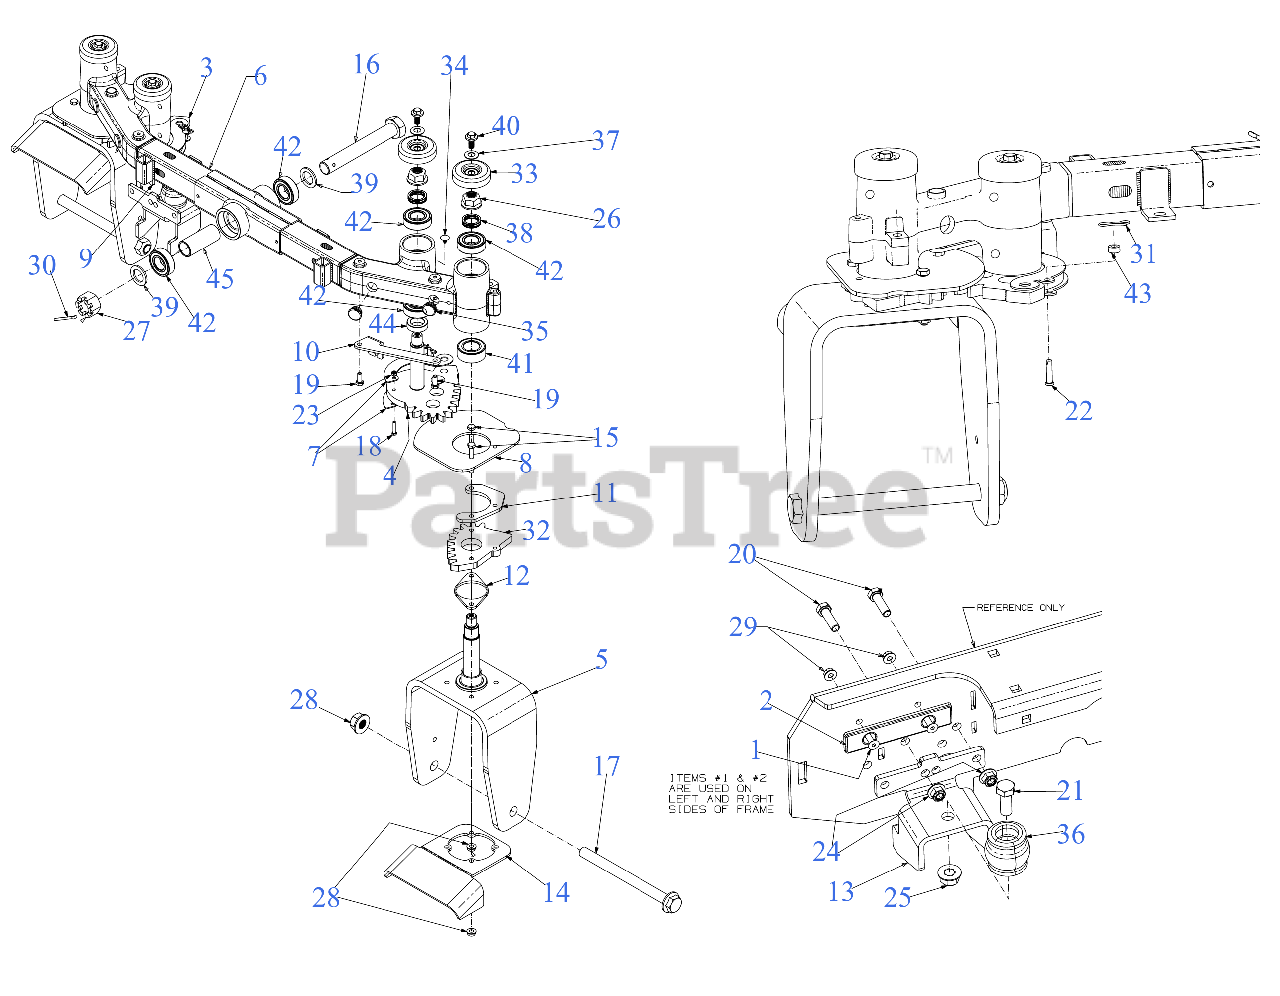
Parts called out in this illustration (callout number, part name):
1	SCREW-FLAT HEAD CA
2	PLATE-LIFT WEAR
3	LEFT HAND STEERING GEAR ASSEMBLY
4	RIGHT HAND STEERING GEAR ASSEMBLY
5	YOKE ASSEMBLY
6	AXLE ASSEMBLY
12	LOWER GEAR SPACER PLATE
13	BUMPER MOUNTING BRACKET
15	HEX SCREW 5/16-18 x 2.25 GR5
16	HEX HEAD SCREW (1-14 x 7 GR5)
17	SCREW 3/4-16 x 9.00 GR5
18	SCREW #10-24 x 1.00 GR5.1
19	SCREW 5/16-18 x .750
20	SCREW 3/8-16 x 1.25 GR5
21	SCREW 1/2-13 x 1.25 GR5
22	CLEVIS PIN .25 x 1.00
26	FLANGE LOCK NUT 3/4-16 TOP LOCK
27	CASTLE NUT 1.0-14 GR5
28	HEX FLANGE NUT
29	LOCK NUT 1/4
30	COTTER PIN
31	BOW TIE COTTER PIN 1/4-5/16
32	STEERING GEAR YOKE
33	AXLE CAP 2.5"
34	RATCHET CLIP
36	AXIAL BUMPER
37	BELL WASHER
38	WAVE WASHER
39	FLAT WASHER 1.005 x 1.570 x 0.125
41	BALL BEARING 30x52x20
42	BALL BEARING (1.0 x 52 x 15)
45	SPACER 1.00 x 1.25 x 2.99
